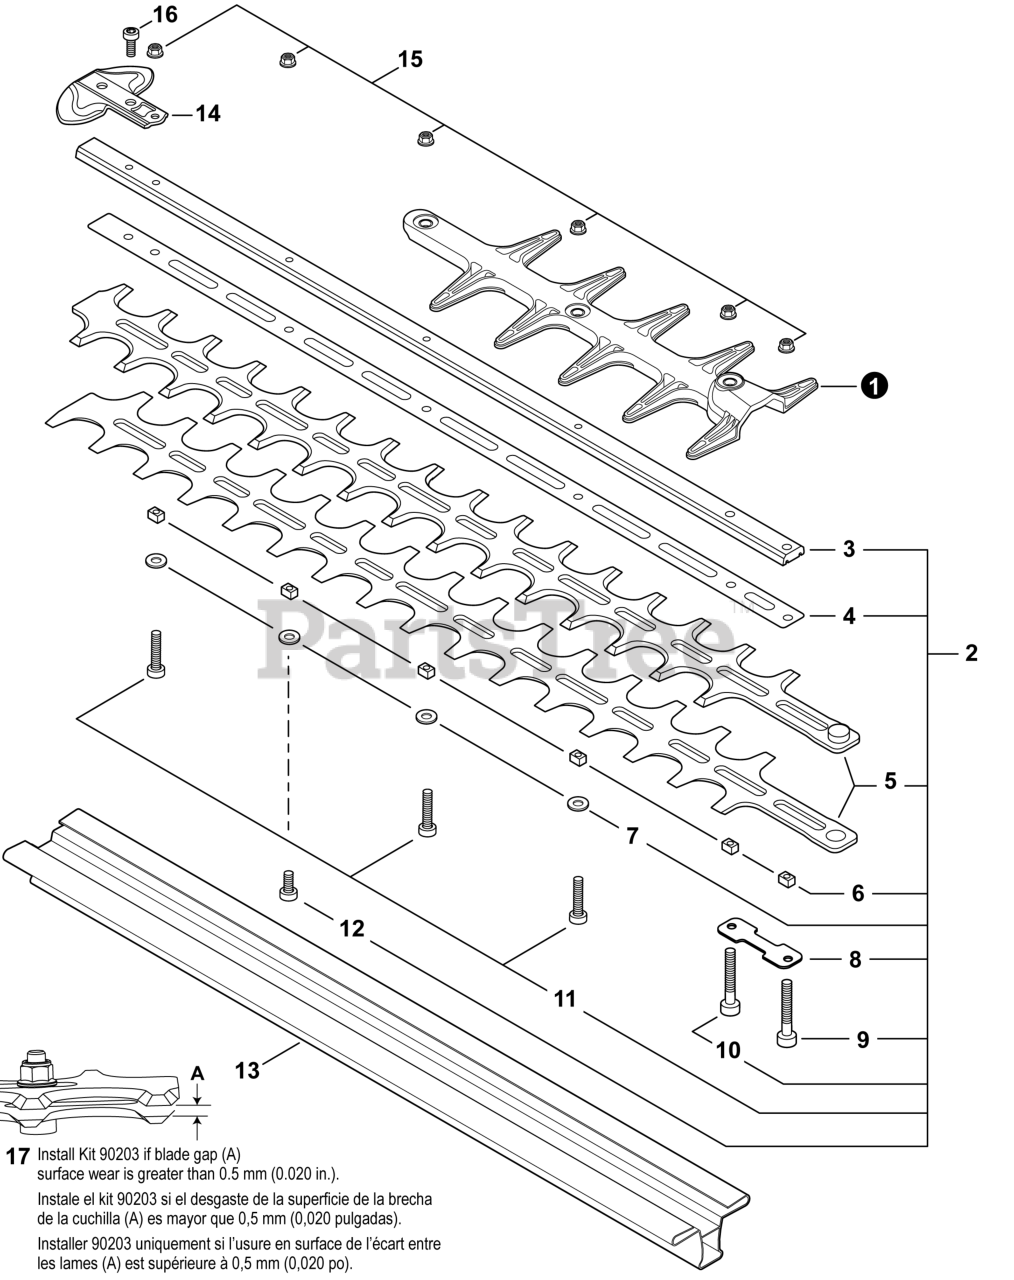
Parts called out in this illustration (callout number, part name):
1	GUARD, CUTTER BLADE
2	CUTTER ASSY, 20"
3	SUPPORT, CUTTER 20"
4	PLATE, CUTTER 20"
5	CUTTER, 20"
6	GUIDE, BLADE 5
8	PLATE, EYE
9	BOLT, TORX 5x30
10	BOLT, TORX 5x35
11	BOLT, TORX 5x25
12	BOLT, TORX 5x20
13	SCABBARD - BLACK
14	GUARD, TIP
15	NUT, FLANGE M5
16	BOLT, TORX 5x8
17	BLADE KIT, ADJUSTABLE
